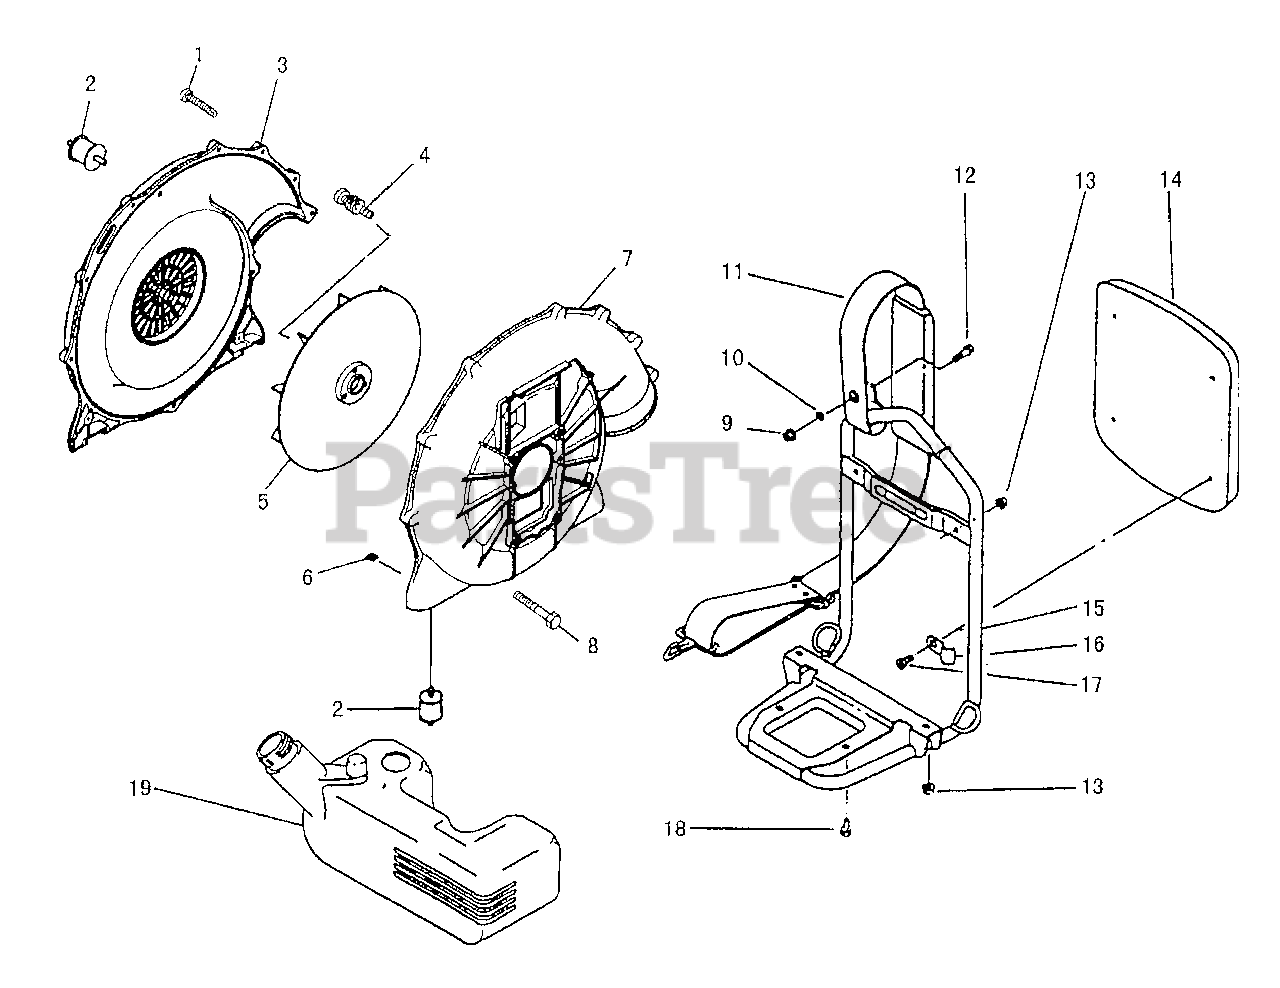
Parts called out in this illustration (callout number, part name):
1	Tapping Screw (M5x30)
2	Anti-Vibe Mount
4	Pre-Coat Lock Bolt
6	Hex Nut
8	Pre-Coat Lock Bolt
9	Flange Nylon Nut (M6)
10	Washer
11	Shoulder Band
12	Truss Screw (M6x20)
13	Flange Nut (M6)
14	Backpack Pad
15	Backpack Frame
16	Backpack Pad Fitting
17	Hex Bolt (M5x12)
18	Screw (M6x10)
